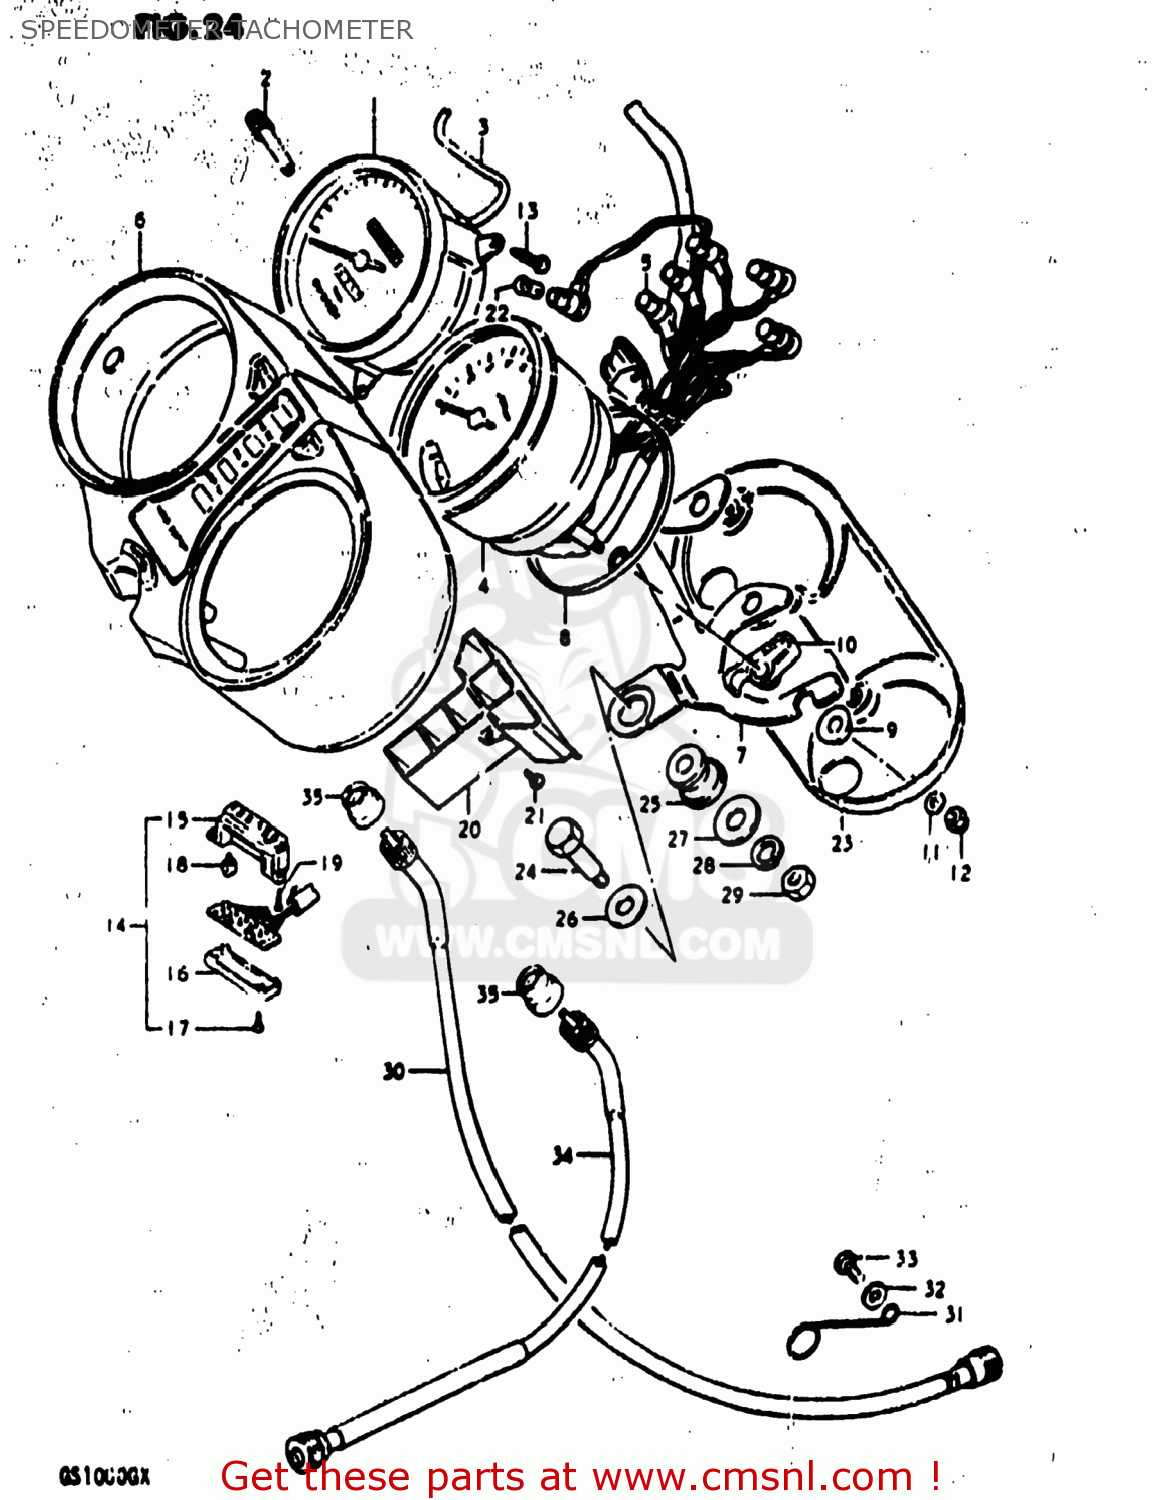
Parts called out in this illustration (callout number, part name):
1	SPEEDOMETER ASSEMBLY
2	KNOB
3	WIRE,LEAD
4	TACHOMETER
5	SOCKET,METER
6	CASE
7	BRACKET,COMBINATION METER
8	PLATE,METER,UNDER
9	CUSHION,METER (A)
10	CUSHION,METER (A)
11	WASHER
12	NUT
13	SCREW
14	INDICATOR ASSEMBLY,GEAR POSITION
15	CASE,GEAR INDICATOR
16	COVER,LWR
17	SCREW,GEAR INDICATOR
18	BULB(14V1.12W)
19	SCREW
20	CASE,PILOT BULB
21	SCREW
22	BULB(12V3.4W,STANLEY,A72A)
23	COVER,UNDER
24	BOLT
25	CUSHION,METER
26	WASHER
27	WASHER (8.5X29X1.6)
28	LOCK WASHER
29	NUT
30	CABLE ASSEMBLY,SPEEDOMETER
31	CLAMP,SPEEDOMETER CABLE
32	WASHER
33	BOLT, UPPER
34	CABLE ASSEMBLY,TACHOMETER
35	SEAL, CABLE END
